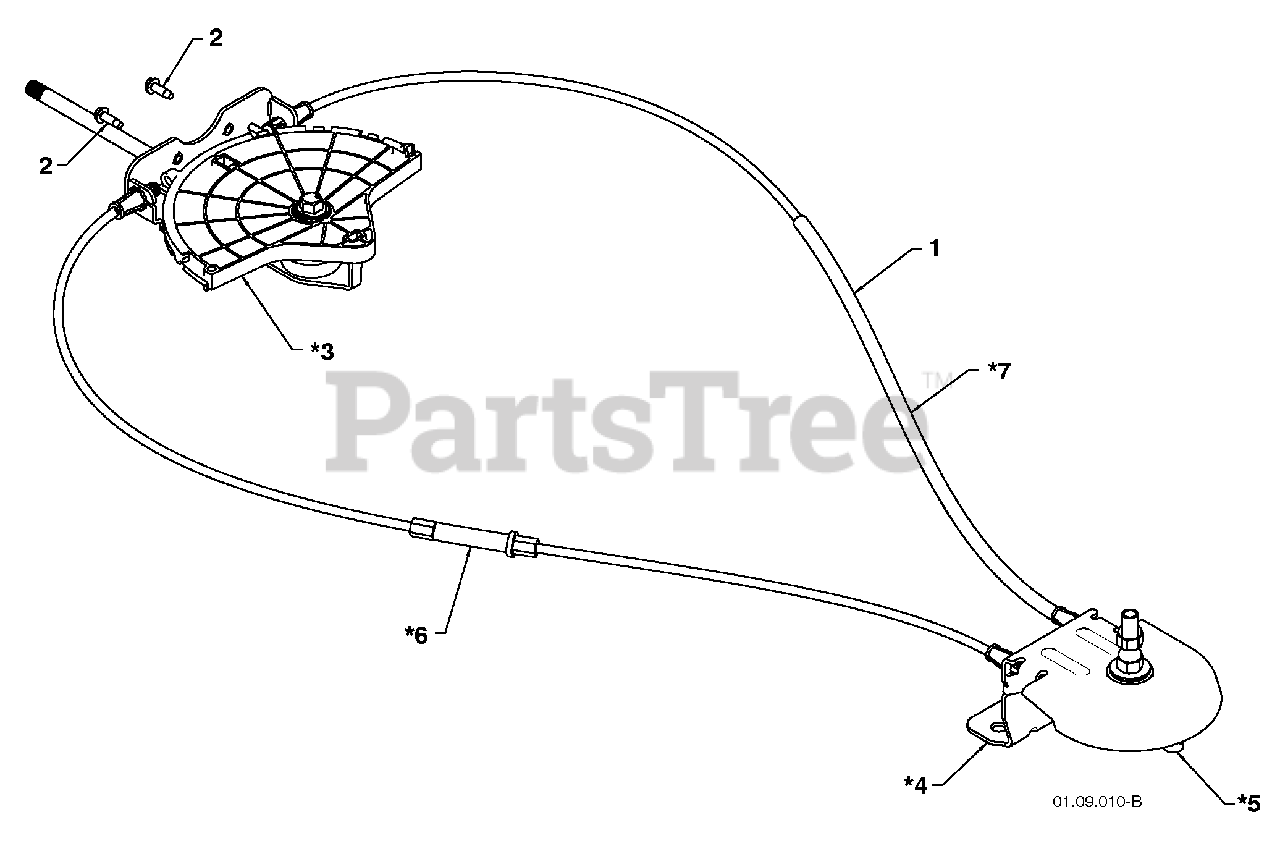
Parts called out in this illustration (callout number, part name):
1	LEVER/CABLE ROTATOR ASSEMBLY
2	SCREW 10-24 X .625
3	ROTATOR HEAD
4	ROTATOR PIVOT BRACKET
5	PULLEY PIVOT
6	CABLE ASSEMBLY ADJUSTABLE
7	CABLE ASSEMBLY HEAT SHIELD
